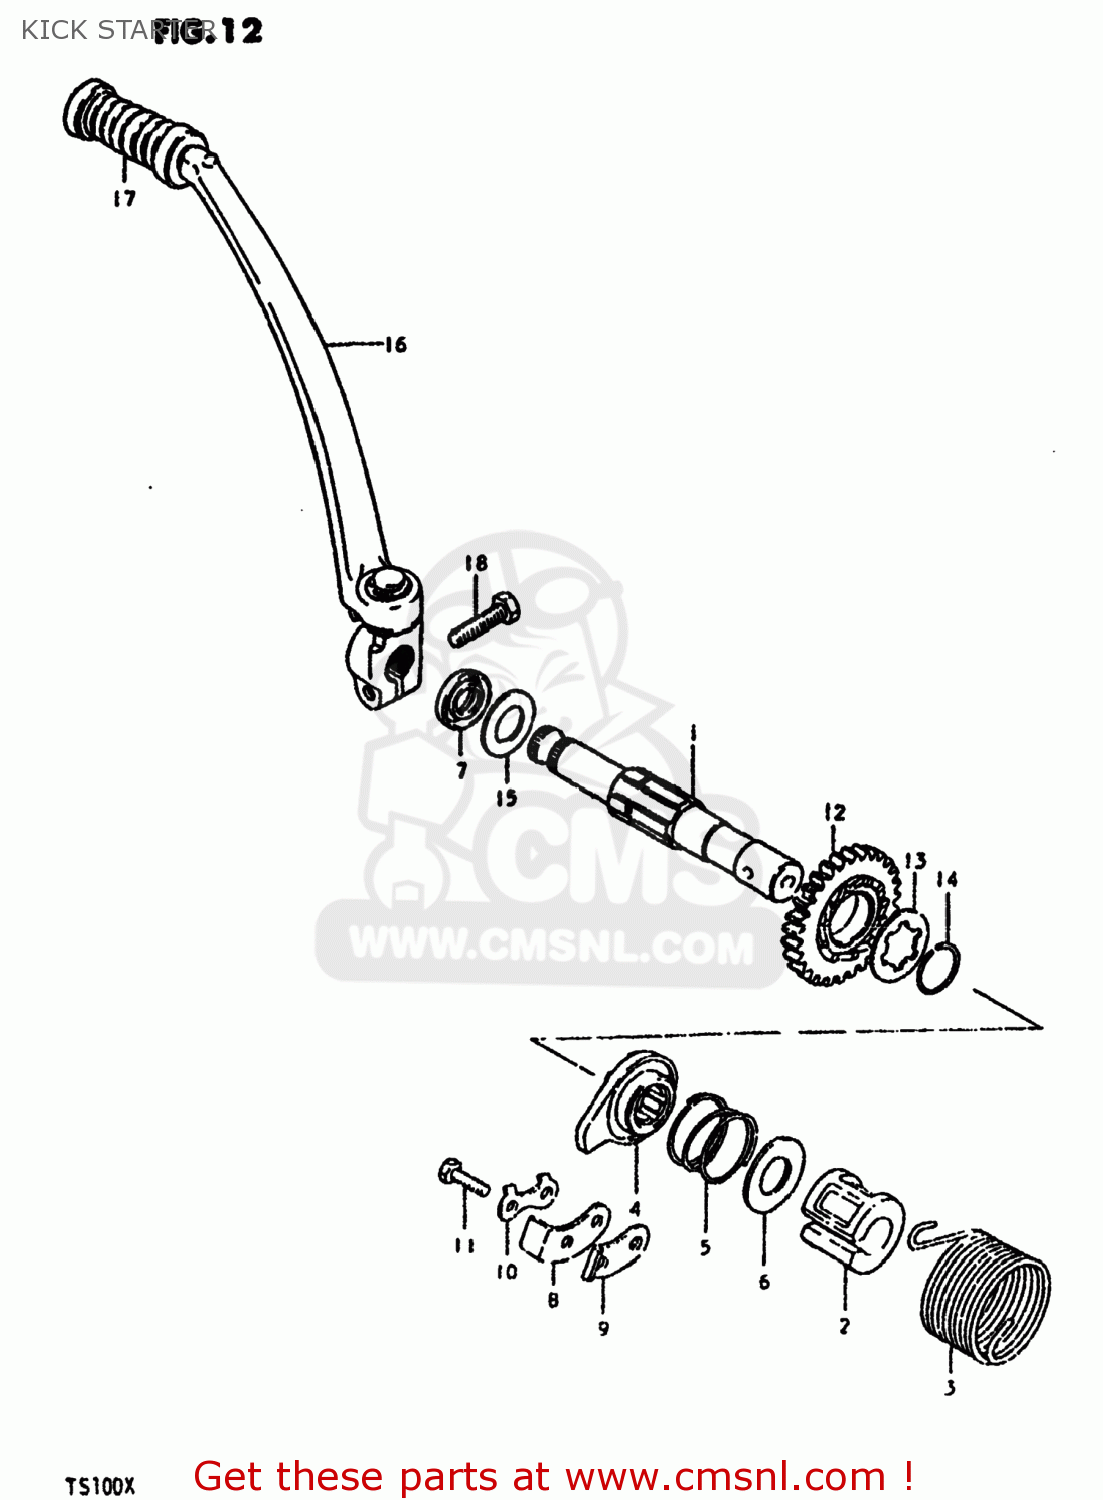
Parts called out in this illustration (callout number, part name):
1	SHAFT,KICK STARTER
2	GUIDE,KICK STARTER SFT SPRING
3	SPRING
4	STARTER,KICK
5	SPRING
6	WASHER
7	SEAL,OIL(16X30X8)
8	GUIDE,KICK STARTER
9	STOPPER,KICK STARTER
10	WASHER
11	BOLT, UPPER
12	GEAR,KICK STARTER DRIVE
13	WASHER,LOCK
14	CIRCLIP
15	WASHER(16X30X1)
16	LEVER ASSEMBLY,KICK STARTER
17	RUBBER,KICK STARTER PEDAL
18	BOLT
